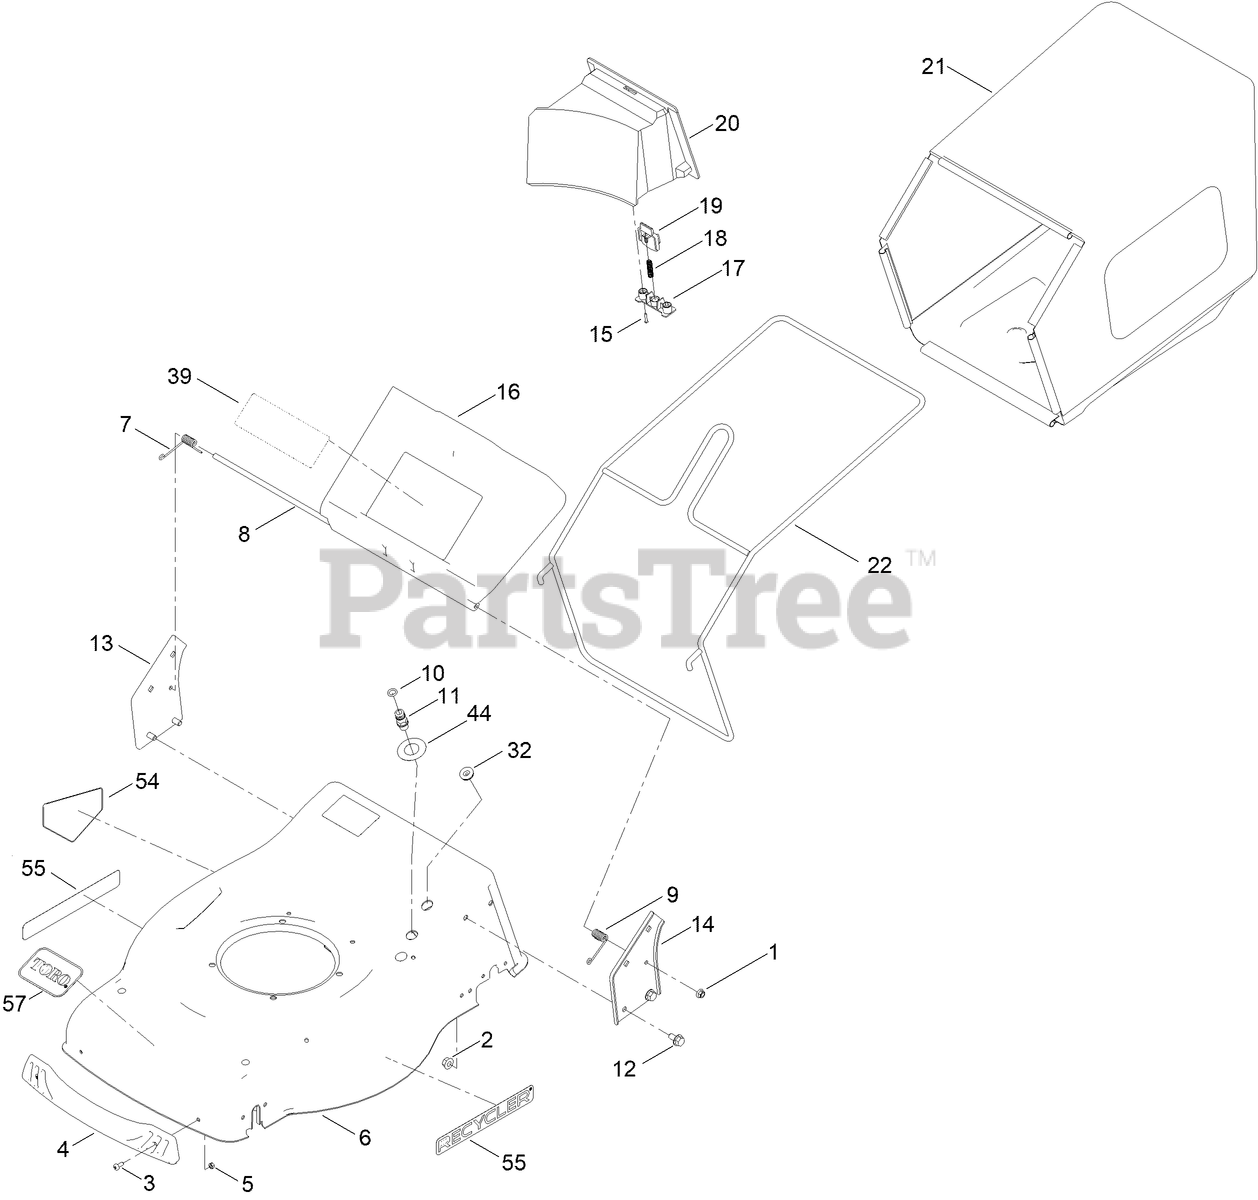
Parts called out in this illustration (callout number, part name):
1	NUT-LOCK, FLANGE
2	NUT-LOCK, FLANGE
3	SCREW-TOOTH
4	BUMPER-FRONT
5	NUT-LOCK
7	SPRING-TWIST, RH
8	ROD-SPRING, REAR DEFLECTOR
9	SPRING-TWIST, LH
10	O-RING
11	PORT-WASH
12	BOLT-HH, FLANGE
13	BRACKET-HANDLE, RH
14	BRACKET-HANDLE, LH
15	SCREW-SELF DRIVING
16	DEFLECTOR-REAR
17	PRESSING BOARD-LOCK BUTTON, MULCH
18	SPRING-BUTTON, MULCH
19	LOCK-BUTTON, MULCH
20	PLUG-MULCH
21	GRASS BAG TORO
22	FRAME-BAG, GRASS
32	SHEATH-CABLE, PROTECTIVE
39	DECAL-SAFETY
44	DECAL-PORT, WASHOUT
54	DECAL-DANGER
